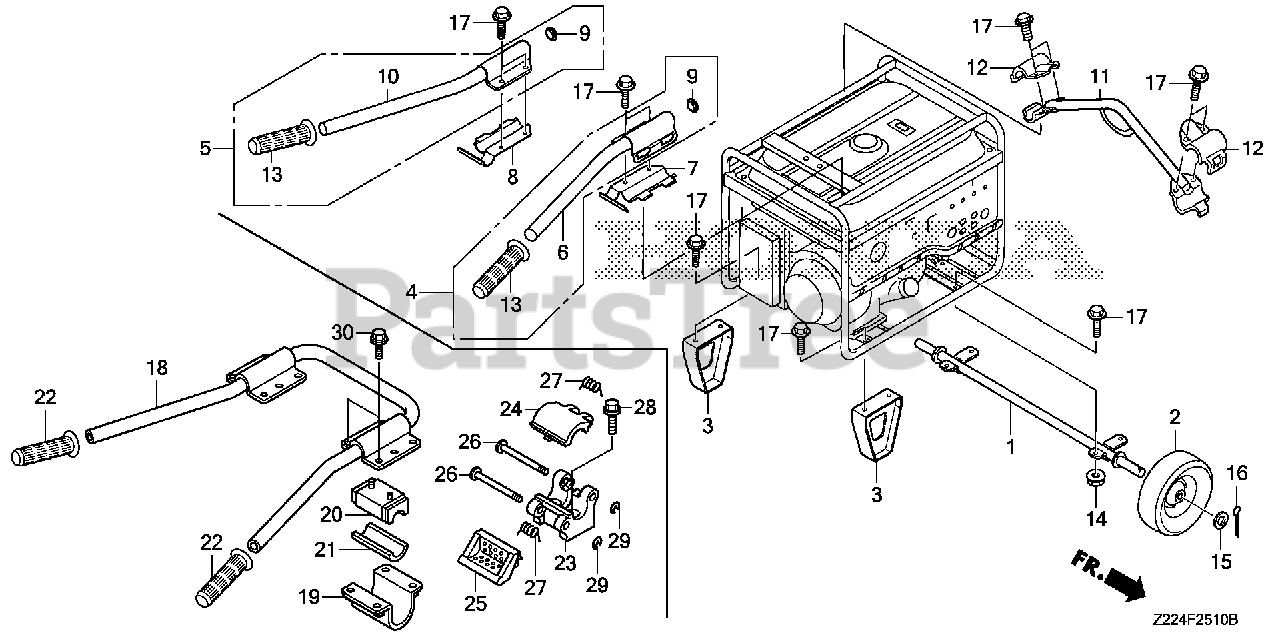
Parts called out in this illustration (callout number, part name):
1	SHAFT, WHEEL *NH105* (MAT BLACK)
2	WHEEL (254X63.5) (COO)(FOR U.S.A.)
2	WHEEL (GLEASON 10"X2.75"=254X70)
3	STAND *NH105* (MAT BLACK)
4	HANDLE ASSY., R. (UPPER) *NH105* (MAT BLACK)
5	HANDLE ASSY., L. (UPPER) *NH105* (MAT BLACK)
6	HANDLE, R. (UPPER) *NH105* (MAT BLACK)
7	BRACKET, R. HANDLE (LOWER) *NH105* (MAT BLACK)
8	BRACKET, L. HANDLE (LOWER) *NH105* (MAT BLACK)
9	CAP, HANDLE (LOWER)
10	HANDLE, L. (UPPER) *NH105* (MAT BLACK)
11	HANGER *NH105* (MAT BLACK)
12	BRACKET, HANGER (UPPER) *NH105* (MAT BLACK)
13	GRIP, HANDLE
14	NUT, FLANGE (8MM)
15	WASHER, PLAIN (20MM)
16	PIN, SPLIT (4.0X28)
16	PIN, SPLIT (4.0X30)
17	BOLT, FLANGE (8X16)
